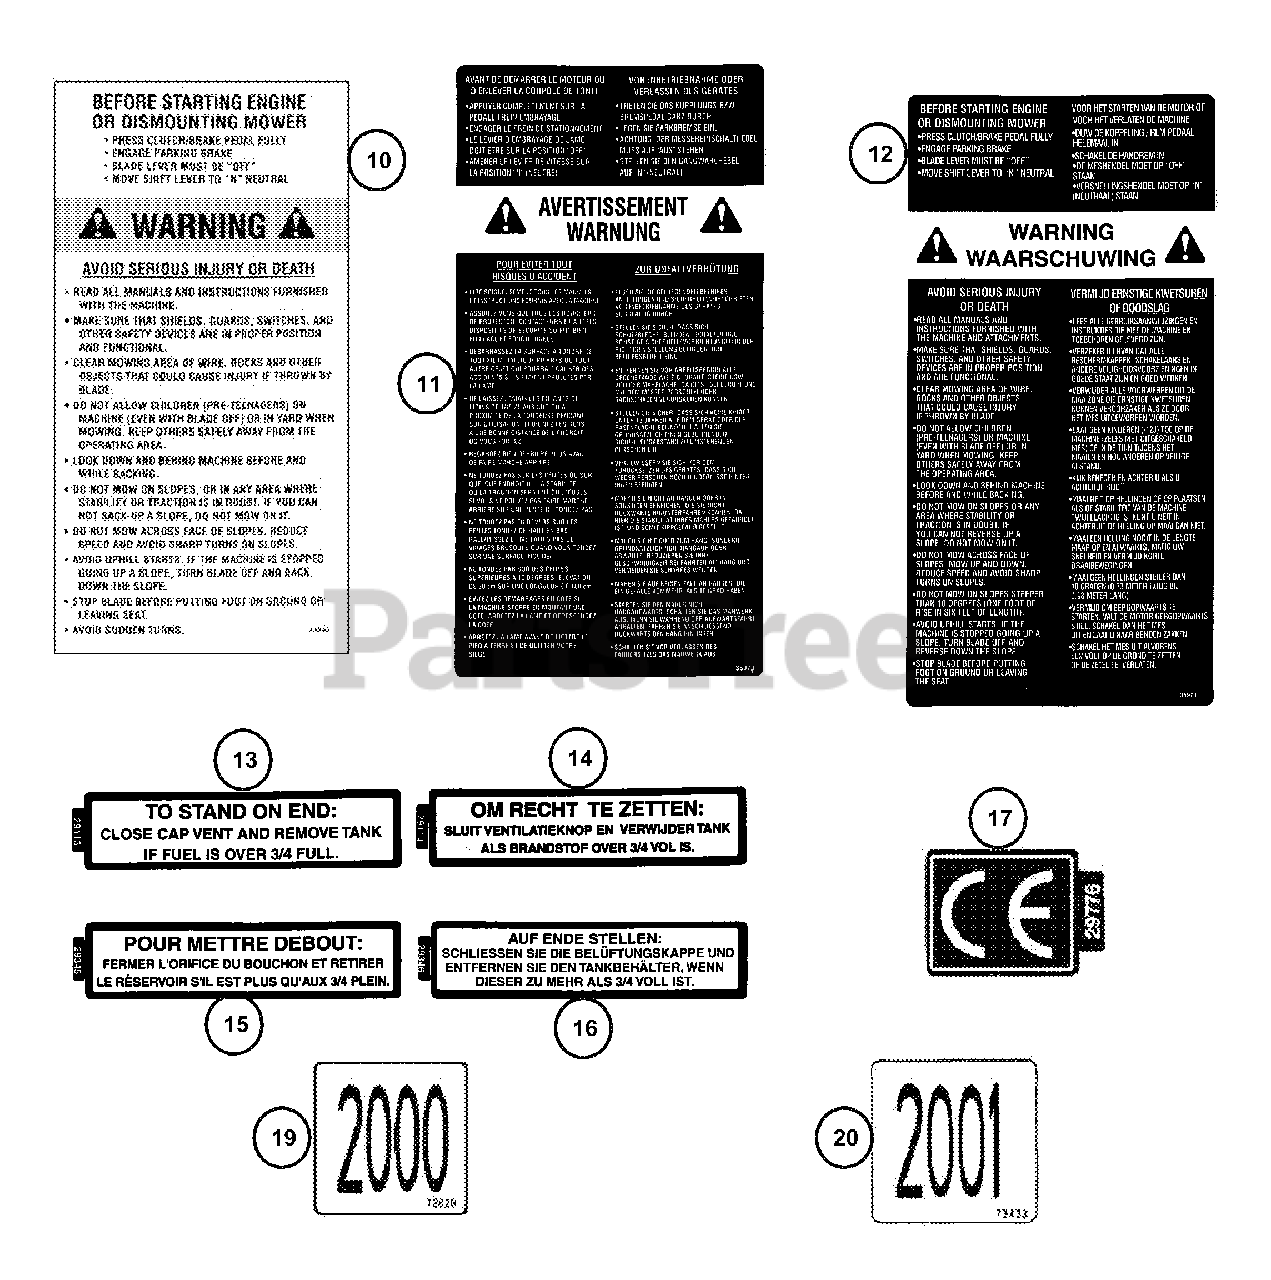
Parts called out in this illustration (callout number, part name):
10	DECAL, Safety Instructions
11	DECAL, Safety Instructions (French/German)
12	DECAL, Safety Instructions (English/Dutch)
13	DECAL, Caution Fuel Leakage (English)
14	DECAL, Caution Fuel (Dutch)
15	DECAL, Caution Fuel (French)
16	DECAL, Caution Fuel (Ger.)
17	DECAL, Euro Community (CE)
19	DECAL, 2000 Year of Mfr.
20	DECAL, 2001 Year of Mfr.
